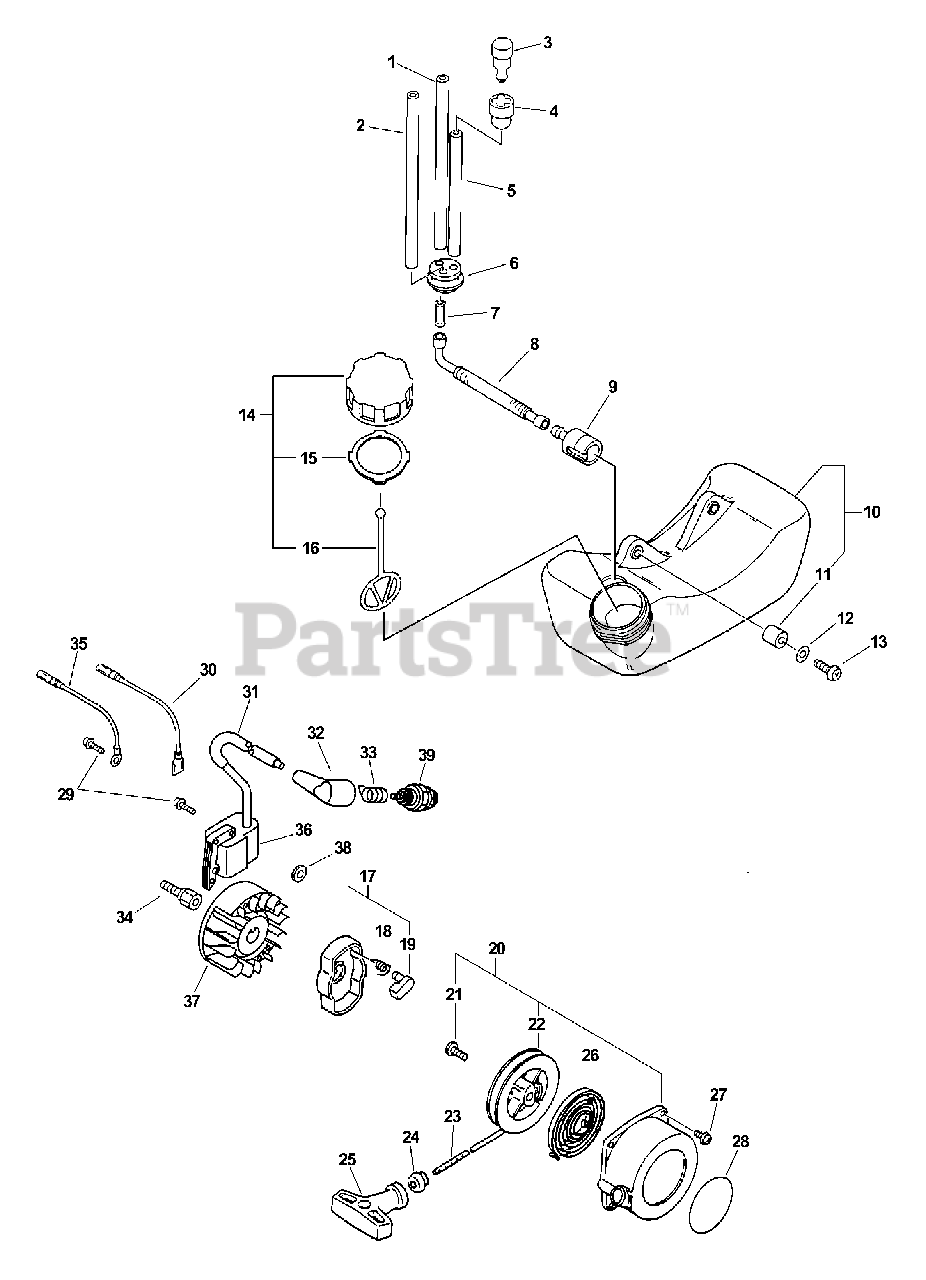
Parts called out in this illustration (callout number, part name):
1	PIPE - 3X5X90 -- BLACK
2	PIPE - 3X6X90 -- CLEAR
3	VENT, FUEL TANK
4	COVER, VENT
5	PIPE - 3X5X70 -- BLACK
6	GROMMET
7	CONNECTOR, PIPE
8	PIPE, FUEL - CORRUGATED
9	FILTER, FUEL
10	FUEL TANK ASSY
12	WASHER - 5
13	SCREW - 5X16
14	CAP ASSY - ORANGE
15	CONNECTOR, CAP
16	CONNECTOR, CAP
17	STARTER PAWL ASSY
18	SPRING, RETURN
19	PAWL, STARTER - BLACK
20	STARTER ASSY
22	REEL, ROPE
23	ROPE, STARTER - 3X1000
24	GUIDE, ROPE
25	GRIP, STARTER
26	SPRING, REWIND
27	SCREW - 4X16
28	LABEL - ECHO
29	SCREW - 4X22
30	LEAD - GROUND
32	CAP, SPARK PLUG
33	TERMINAL, SPARK PLUG CAP
34	HUB, FAN
35	LEAD - IGNITION
36	COIL, IGNITION
37	FLYWHEEL
38	SPACER
39	SPARK PLUG -- BPM-7Y
39	SPARK PLUG -- BPMR-7A
